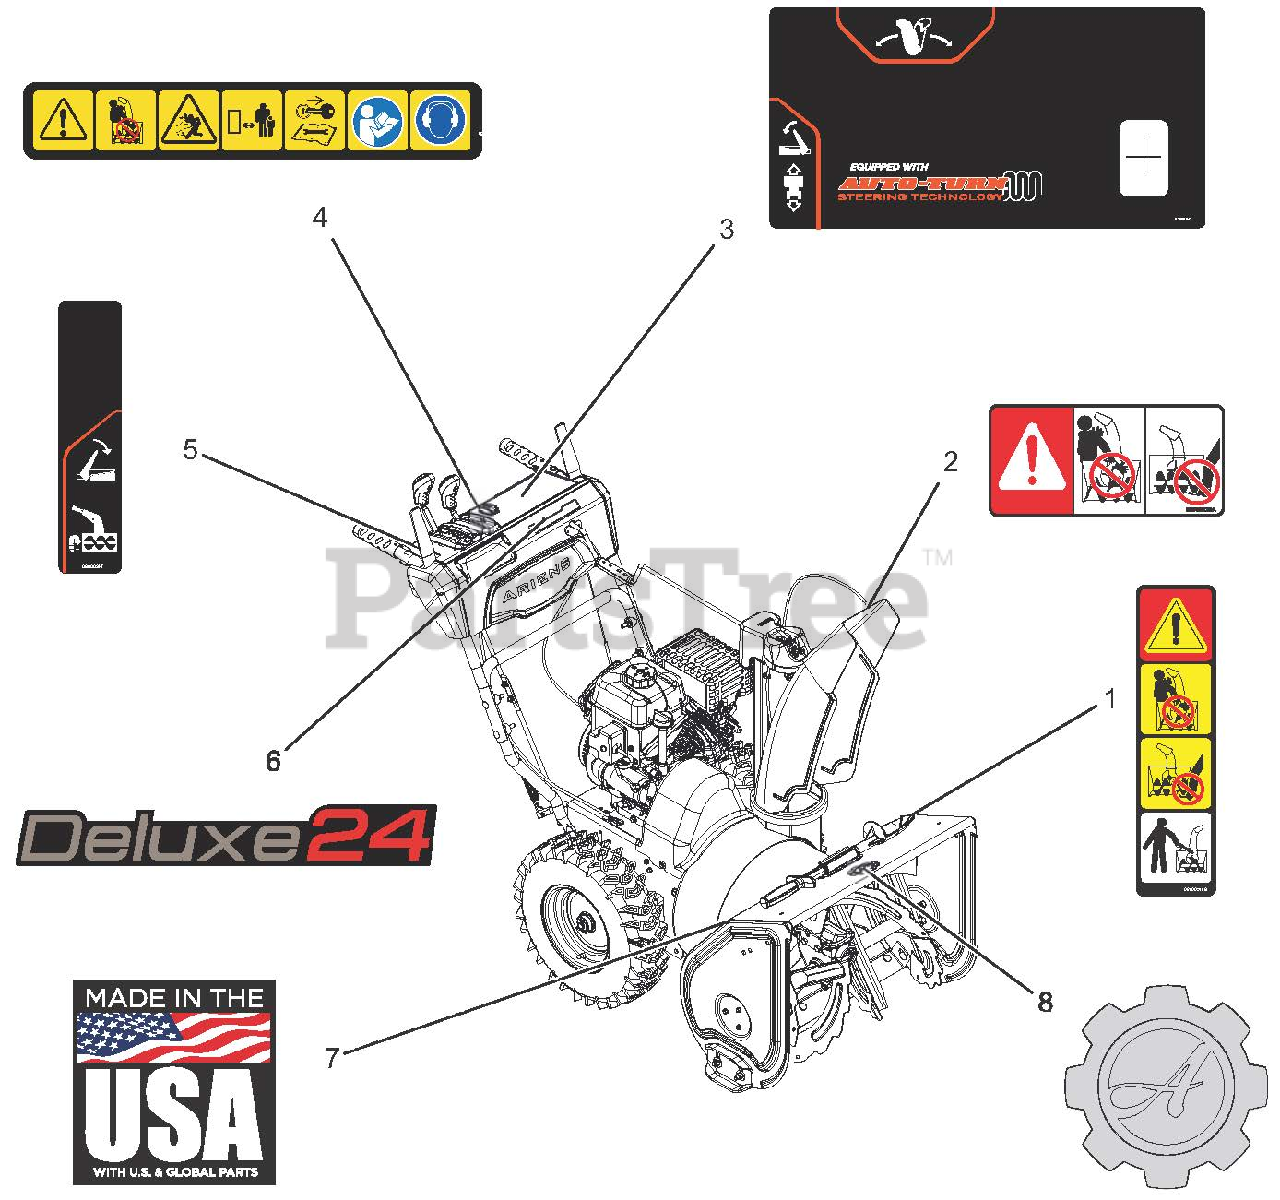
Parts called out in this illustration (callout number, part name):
1	DECAL, DANGER - ROTATING PARTS
2	DECAL, DANGER
3	DECAL,CONTROL-LG ID
4	DECAL,DASH - SAFETY
5	DECAL,CONTROL-RH CONTROL
6	DECAL, DASH - DELUXE 24
7	DECAL, MADE IN USA
8	DECAL, ARIENS-GEAR BADGE
